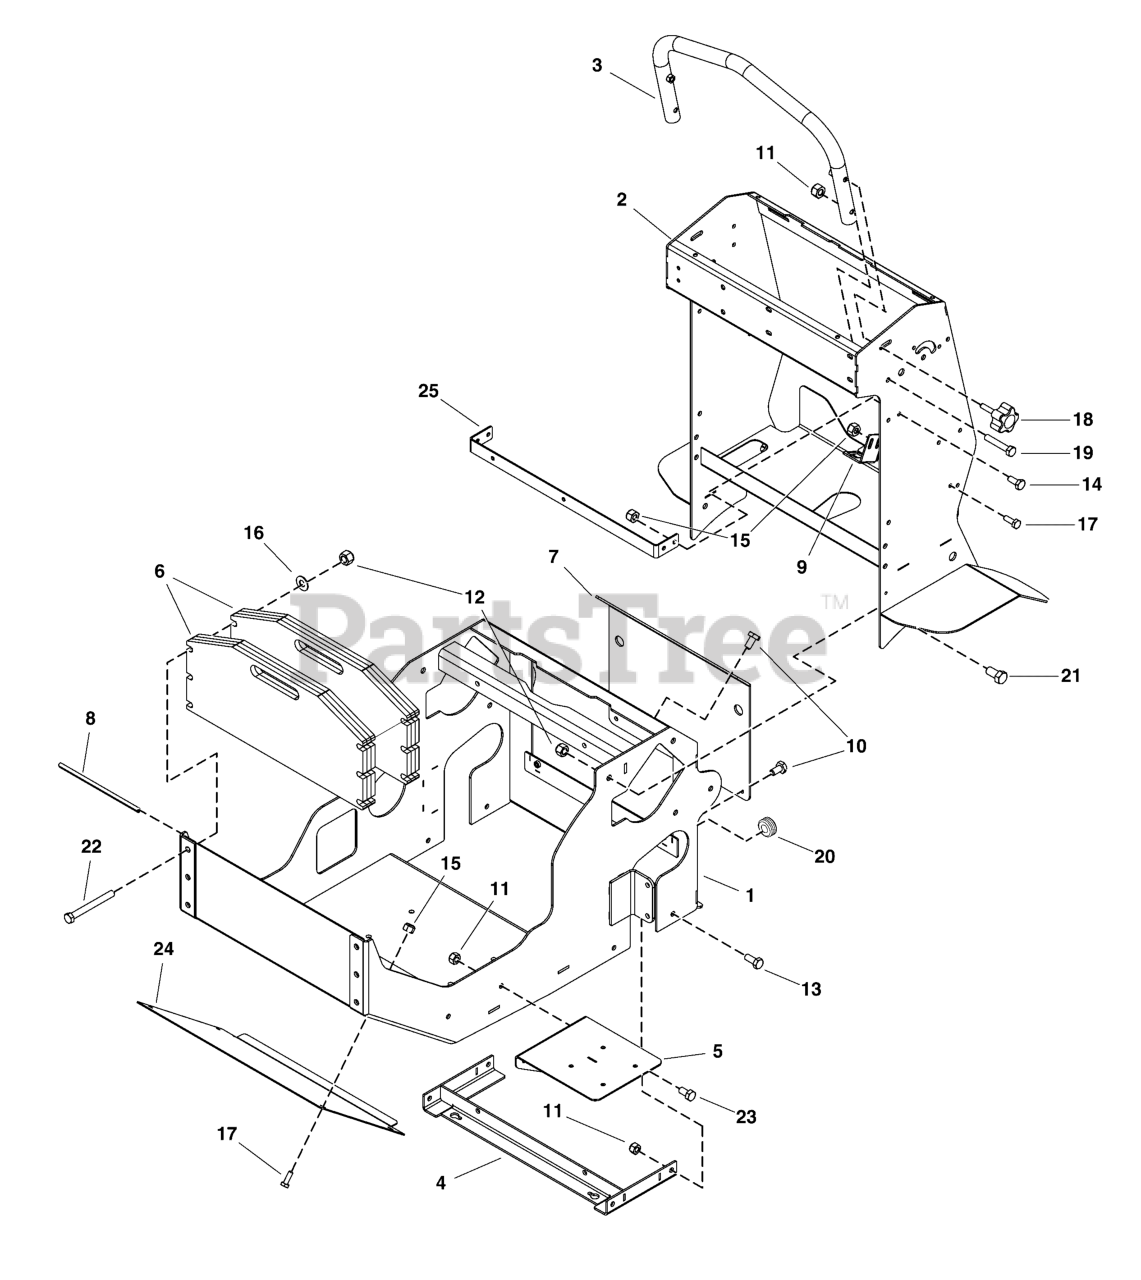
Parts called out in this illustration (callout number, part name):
1	WELD, MAIN FRAME LOWER
2	WELD, HAND CONTROLS
3	WELD, STATIONARY HANDLEBAR
4	WELD, LOWER MOUNT TRANSAXLE
5	WELD, BATTERY SUPPORT PLATE
6	WELD, PLATE COUNTER WEIGHT
7	PLATE, BACK, (SANDED)
8	TRIM FOR CONSOLE, 7 INCH
9	PLATE, PARKING BRAKE SWITCH
10	SCR-CAP, HEX .250"-20 X .500" SS188
11	NUT-HEX-NYLK, 0.3125"-18 SS188
12	NUT-HEX-NYLK, .375"-16 SS188
13	SCR-CAP, HEX .3125"-18 X .750" SS188
14	SCR-CAP, HEX .250"-20 X .625" SS188
15	NUT-HEX-NYLK, .250"-20 SS188
16	WSHR-STL, FLT .406" X .875" X .050" IS SS188
17	SCR-CAP, HEX .250"-20 X .750" SS188
18	KNOB, STATIONARY CONTROL BAR
19	SCR-CAP, HEX .3125"-18 X 1.750" SS188
20	GROMMET, 0.375" I.D., FIT 0.500" HOLE
21	SCR-CAP, HEX .375"-16 X .750" SS188
22	SCR-CAP, HEX .375"-16 X 3.500" SS188
23	SCR-CAP, HEX .3125"-18 X .625" SS188
24	PLATE, FRONT ENGINE COVER
25	BRACKET, EXPANSION TANK MOUNT
